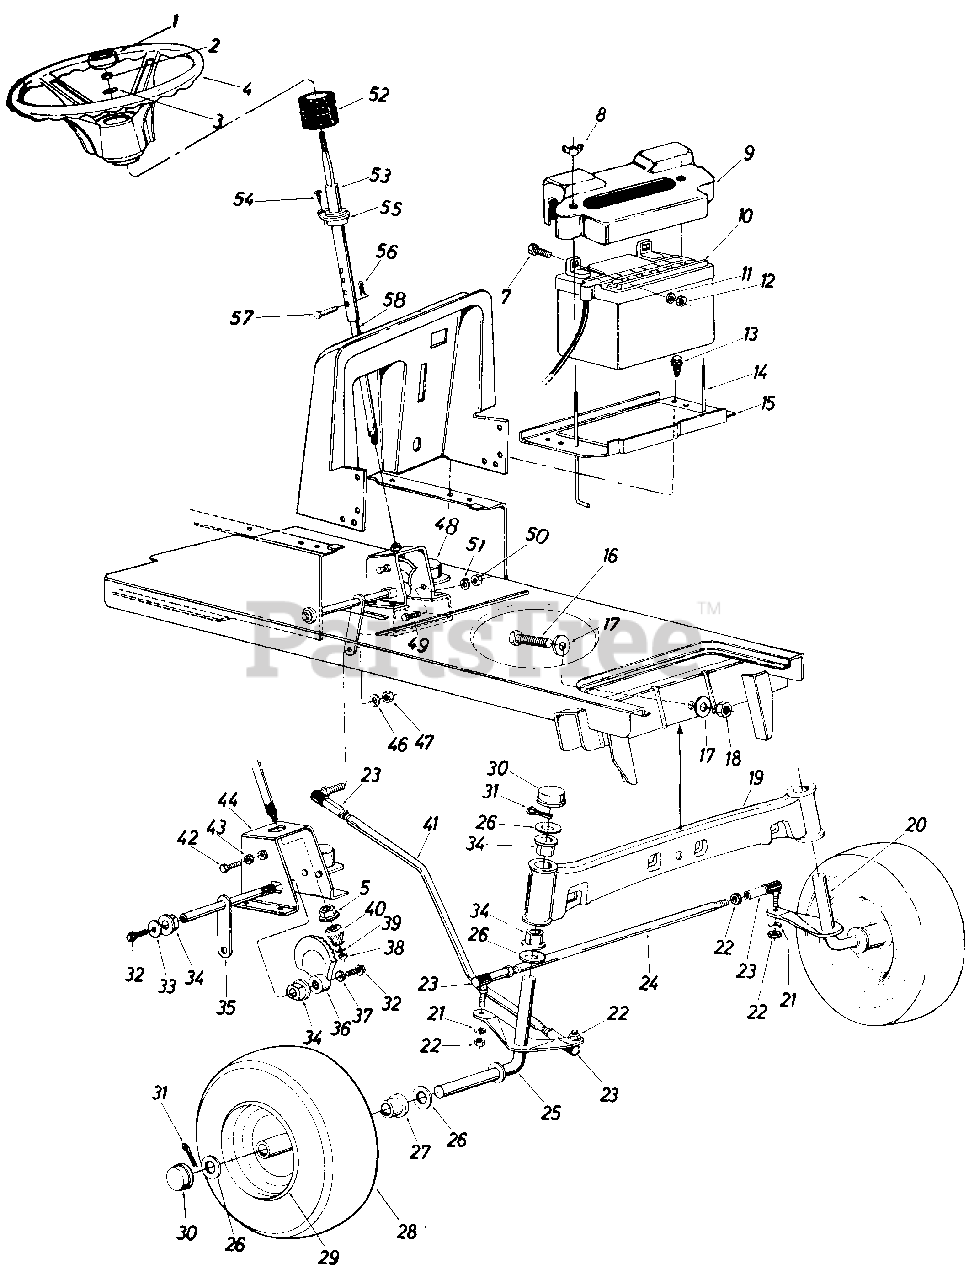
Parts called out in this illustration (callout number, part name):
1	Steering Wheel Cap
2	Hex Cent. L-Nut 5/16-18 Thd.
3	Bell-Wash. 5/16" I.D. x .87" O.D. x .060
4	Steering Wheel
7	Hex Scr. 1/4-20 x .62" Lg.
8	Wing Nut Plastic 1/4-20 Thd.
9	Battery Cover
10	12-V Battery
11	L-Wash. 1/4" Scr.
12	Hex Nut 1/4-20 Thd.
13	Hex Thd. Rolling Scr. 1/4-20 x .50" Lg.
14	Battery Hold Down Rod
15	Battery Plate
16	Hex Scr. 5/8-18 x 2.50" Lg.
17	Flat Wash. .66" I.D. x 2.25" O.D. x .17
18	Hex Cent. L-Nut 5/8-18 Thd.
19	Front Pivot Bar Ass'y.
20	Front Axle Ass'y. L.H.
21	L-Wash. 3/8" Scr.
22	Hex Jam Nut 3/8-24 Thd.
23	Ball Joint Ass'y.
24	Tie Rod
25	Front Axle Ass'y. R.H.
26	Fl-Wash. .780 I.D. x 1.59 O.D.
27	Flange Bearing
28	Front Wheel Ass'y. Comp.
30	Dust Cover
31	Cotter Pin 5/32" Dia. x 1.00" Lg.
32	Hex Scr. 3/8-24 x .75" Lg. Grade 5
33	Fl-Wash. 3/8 I.D. x 1.25 O.D. x .090
34	Flange Double " D" Brg. .753 I.D.
35	Steering Arm Shaft Ass'y.
36	Side Gear Steering
37	Bell-Wash. 3/8" I.D.
38	Hex Cent. L-Nut 5/16-24 Thd.
39	Fl-Wash. 5/16" I.D. x .62 O.D. x .059
40	Pinion Gear Steering
41	Drag Link
42	Hex Nylon Scr. 3/8-16 x 1.25" Lg.
43	Hex Nut 3/8-16 Thd.*
44	Steering Gear Sup. Ass'y.
46	L-Wash. 3/8" Scr.
47	Hex Nut 3/8-24 Thd.
48	Solenoid
49	Hex Scr. 1/4-20 x .62" Lg.
50	Hex Nut 1/4-20 Thd.
51	L-Wash. 1/4" Scr.
52	Steering Bellow
53	Upper Steering Shaft
54	Oval Hd. Cr.-Sunk Scr. #10 x 5/8" Lg.
55	Fl-Bearing .89" I.D. x 1.36" O.D.
56	Hairpin Cotter
57	Clevis Pin
58	Lower Steering Shaft
